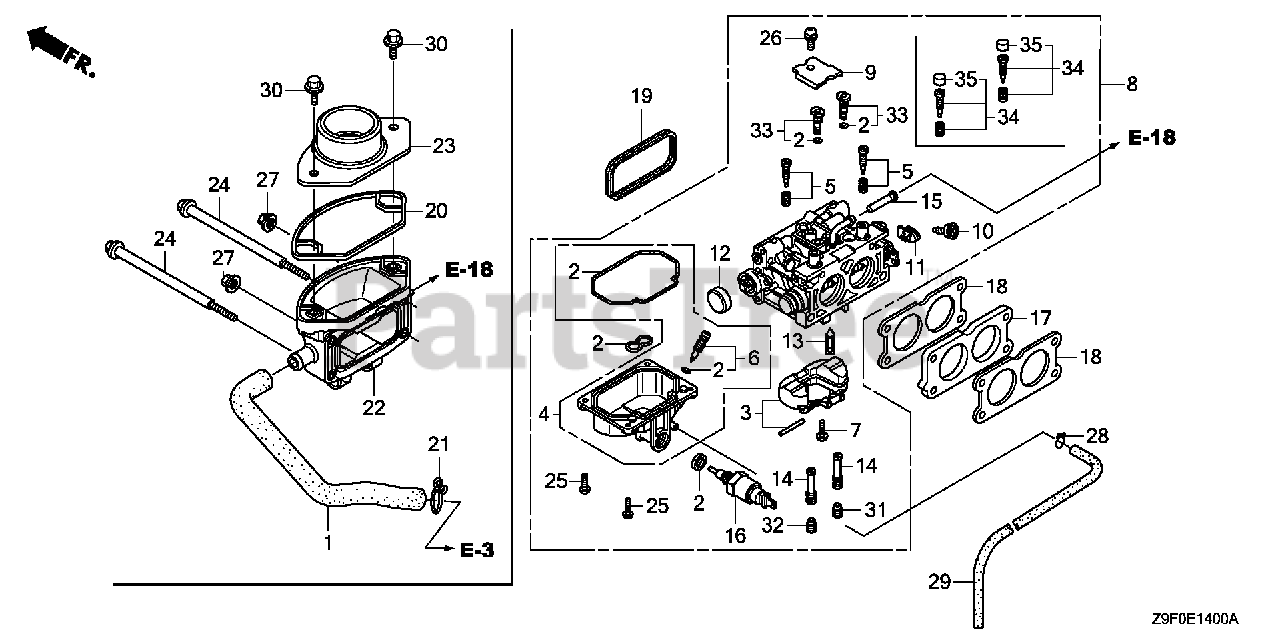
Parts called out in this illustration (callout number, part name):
2	GASKET SET
4	CHAMBER SET, FLOAT
6	SCREW SET, DRAIN
7	SCREW, FLOAT
8	CARBURETOR ASSY. (BK06B A)
8	CARBURETOR ASSY. (BK06B C)
10	SCREW, THROTTLE STOP
11	ARM, THROTTLE LINKAGE
12	CAP, CHOKE DUST
13	VALVE, FLOAT
14	NOZZLE, MAIN
15	SCREEN, FUEL STRAINER
16	VALVE ASSY., SOLENOID
17	INSULATOR, CARBURETOR
18	GASKET, CARBURETOR
19	GASKET, AIR CLEANER
25	SCREW, PAN (4X12)
26	SCREW-WASHER (5X10)
28	CLIP, TUBE (B8)
29	BULK HOSE, VACUUM (4.5X1000) (4.5X350)
31	JET, MAIN (#98)
31	JET, MAIN (#102)
31	JET, MAIN (#110)
32	JET, MAIN (#102)
32	JET, MAIN (#108)
32	JET, MAIN (#115)
33	JET SET, PILOT (#40)
34	SCREW SET (CARBURETOR NO.)
35	CAP, ADJUSTING SCREW (CARBURETOR NO.)
